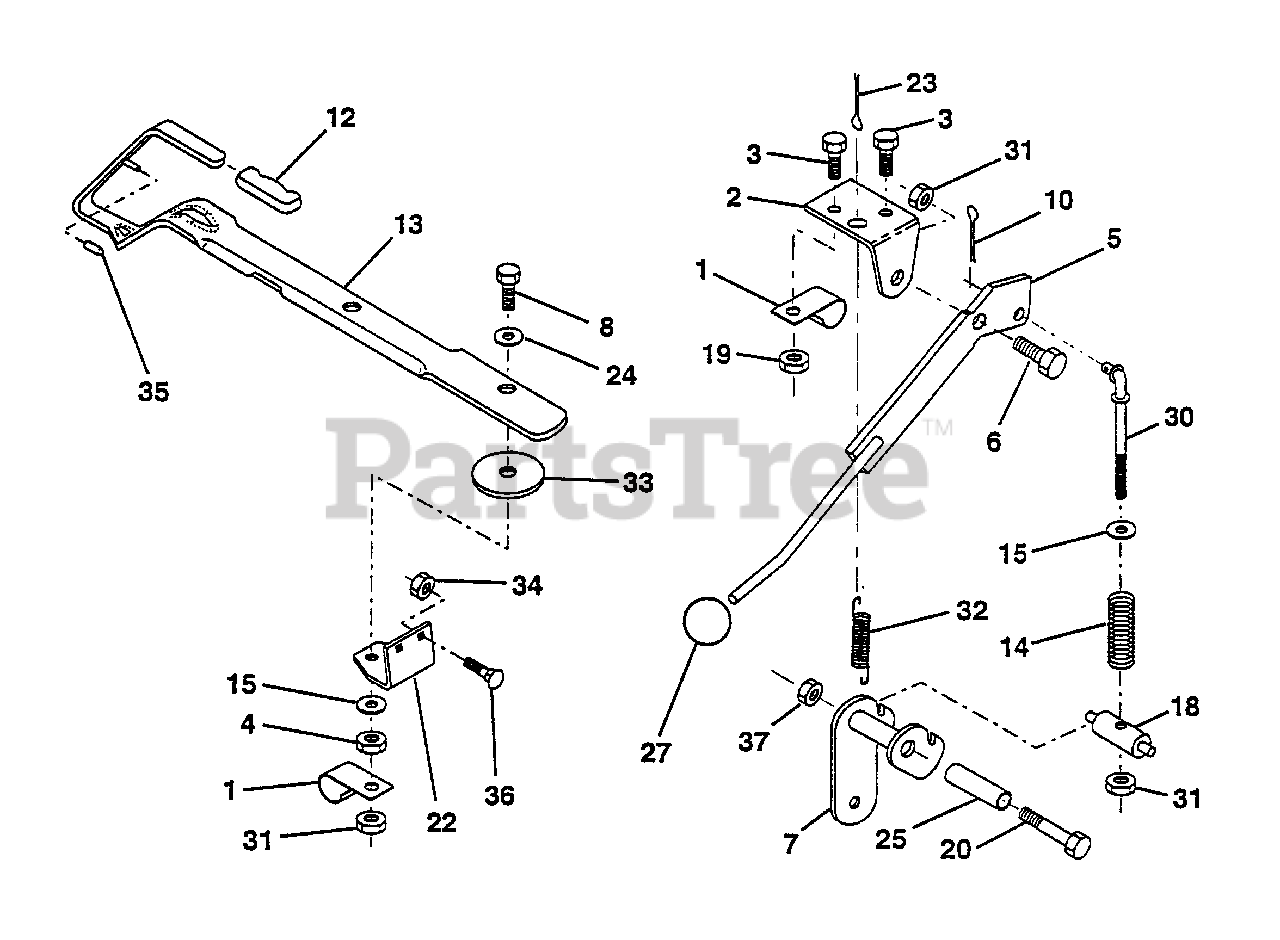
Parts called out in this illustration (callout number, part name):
1	Clip, Insulated
2	Bracket, Mower Clutch
3	Bolt, Hex Head, Fin. 1/4-20 UNC x 1/2 Grade 5
4	Nut, Centerlock
5	Assembly, Clutch Lever
6	Bolt, Shoulder
7	Assembly, Mower Clutch Arm
8	Bolt, Hex Head 3/8-16 UNC x 1-1/2
10	Pin, Cotter 1/8 x 3/4
12	Handle, Lift Lever
13	Assembly, Lift Handle
14	Spring, Compression
15	Washer 13/32 x 1 x 11 Gauge
18	Trunnion, Threaded 3/8-16
19	Nut, Crownlock 1/4-20
20	Bolt, Hex Head, Fin. 3/8-16 UNC x 2-3/4
22	Bracket, Lift Lever
23	Pin, Cotter 3/32 x 3/4
24	Washer 25/64 x 1-1/4 x 12 Gauge
25	Tube, Spacer
30	Rod, Tension, Clutch
31	Nut Lock Hex w/wsh 3/8 -16
32	Spring, Extension, Return
33	Washer .390 x 1.437 x .074
34	Nut, Lock Hx w/Ins 5/16-18
35	Cap, Vinyl, Red
36	Bolt, Carriage 5/16-18 x 314
37	Nut Crownlock 3/8-16
